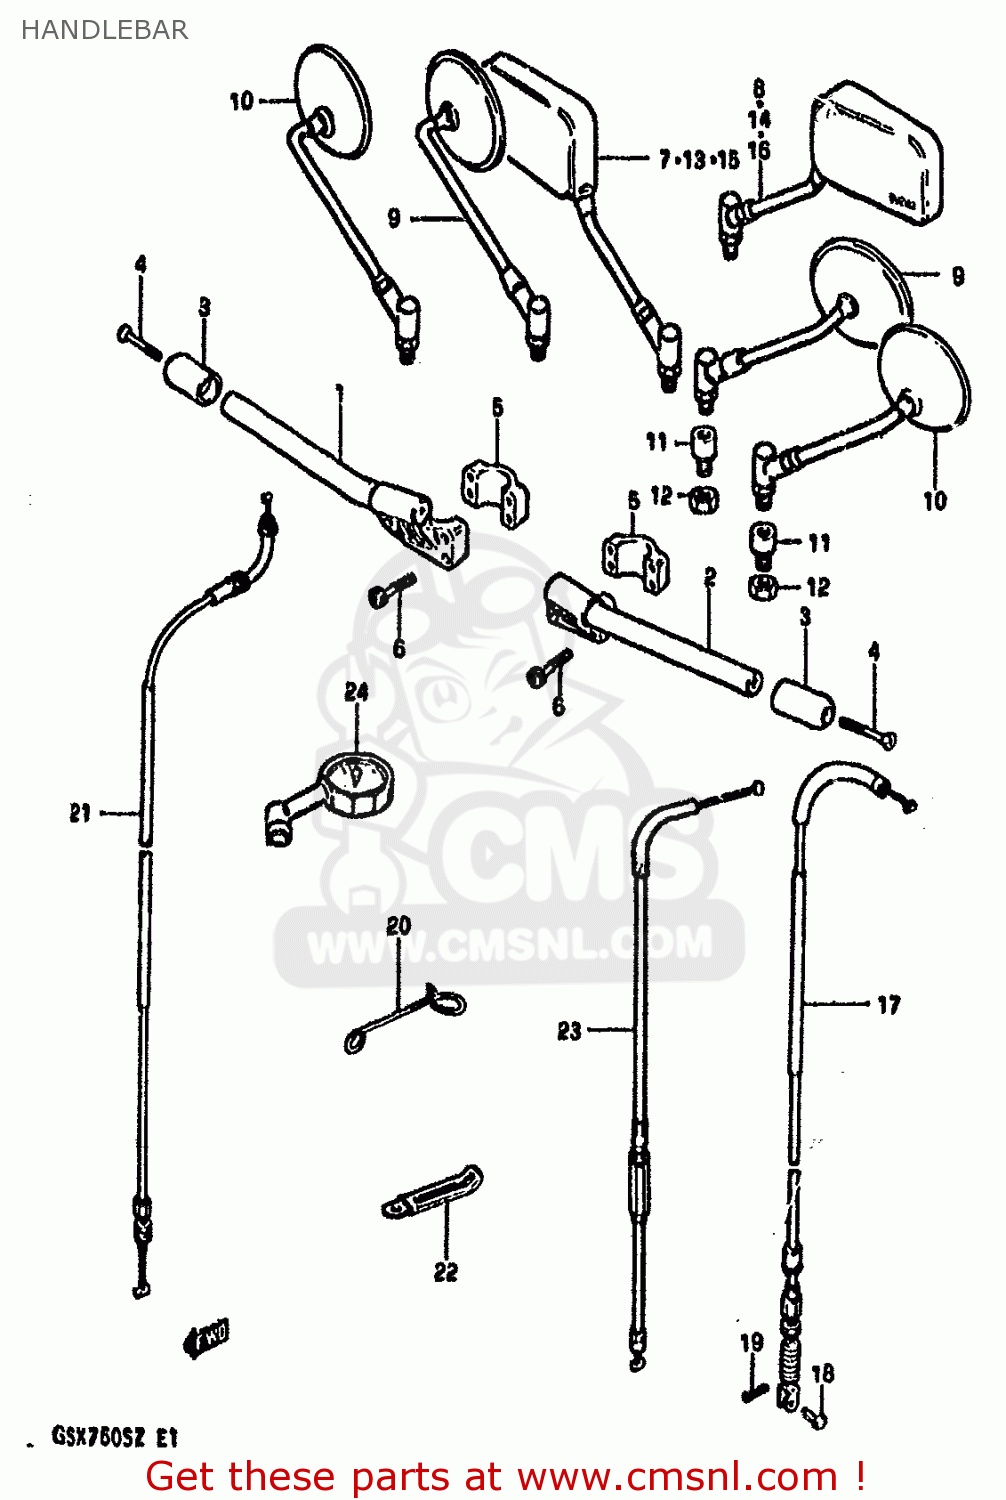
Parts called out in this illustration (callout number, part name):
1	HANDLEBAR,R
2	HANDLEBAR,L
3	BALANCER,HANDLEBAR
4	SCREW
5	HOLDER,HANDLEBAR
6	BOLT
7	MIRROR ASSEMBLY,REAR VIEW
8	MIRROR ASSEMBLY,REAR VIEW
9	MIRROR ASSY,RH
10	MIRROR ASSY,RH
11	CUSHION,REAR VIEW MIRROR
12	NUT
13	MIRROR, REAR VIEW RH
14	MIRROR ASSY,LH
15	MIRROR, REAR VIEW RH
16	MIRROR, REAR VIEW LH
17	CABLE ASSY,CLUTCH
18	PIN(L:15)
19	PIN
20	GUIDE,CLUTCH CABLE
21	CABLE ASSEMBLY,THROTTLE
22	CLAMP
23	CABLE,CLUTCH
24	GAUGE ASSY,AIR PRESSURE
